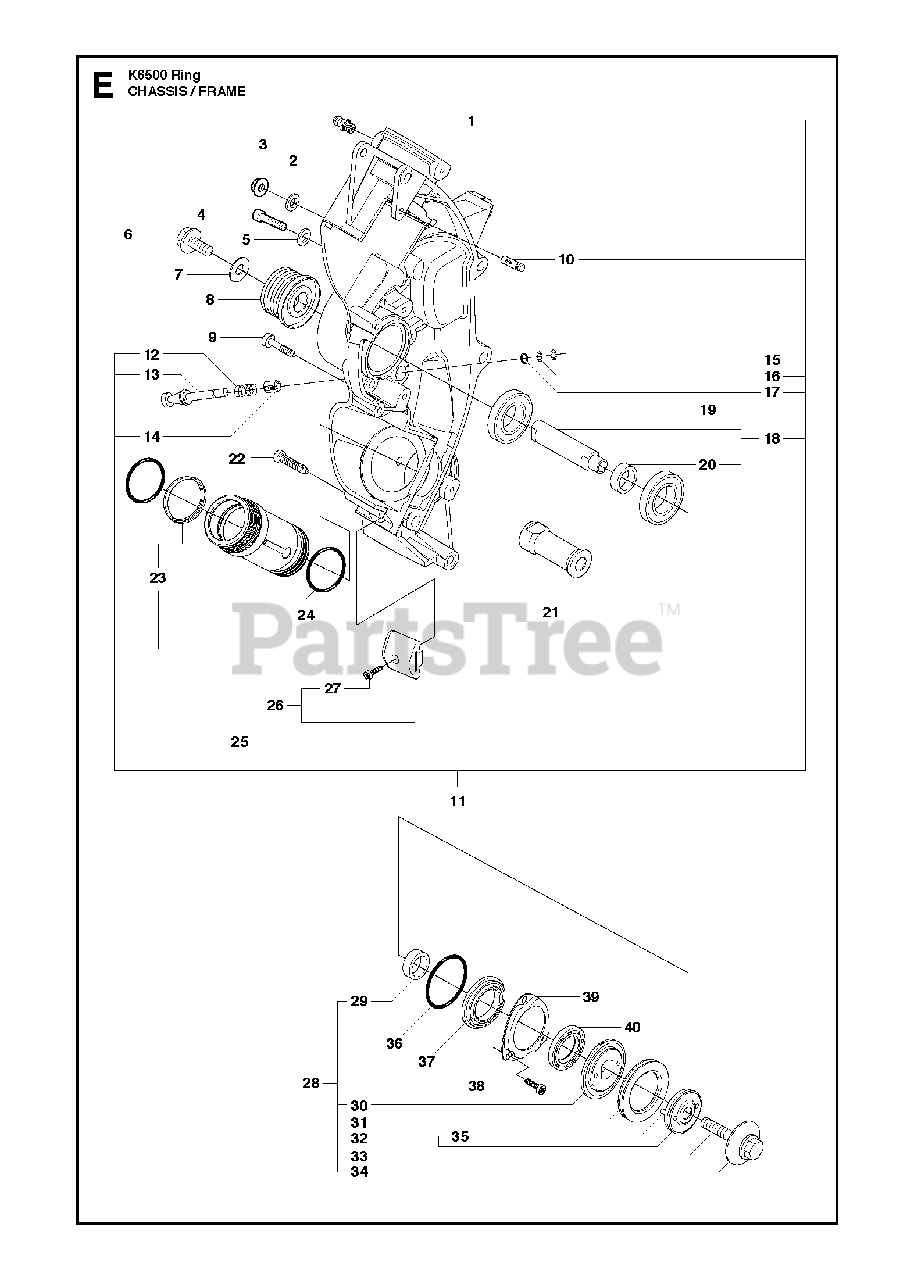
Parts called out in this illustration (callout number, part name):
1	LUBRICATION NIPPLE
9	SCREW ITXSCM
19	BALL BEARING
22	SCREW ITXSCM
27	SCREW ITXSCM
38	SCREW ITXSCM
40	SEALING RING
